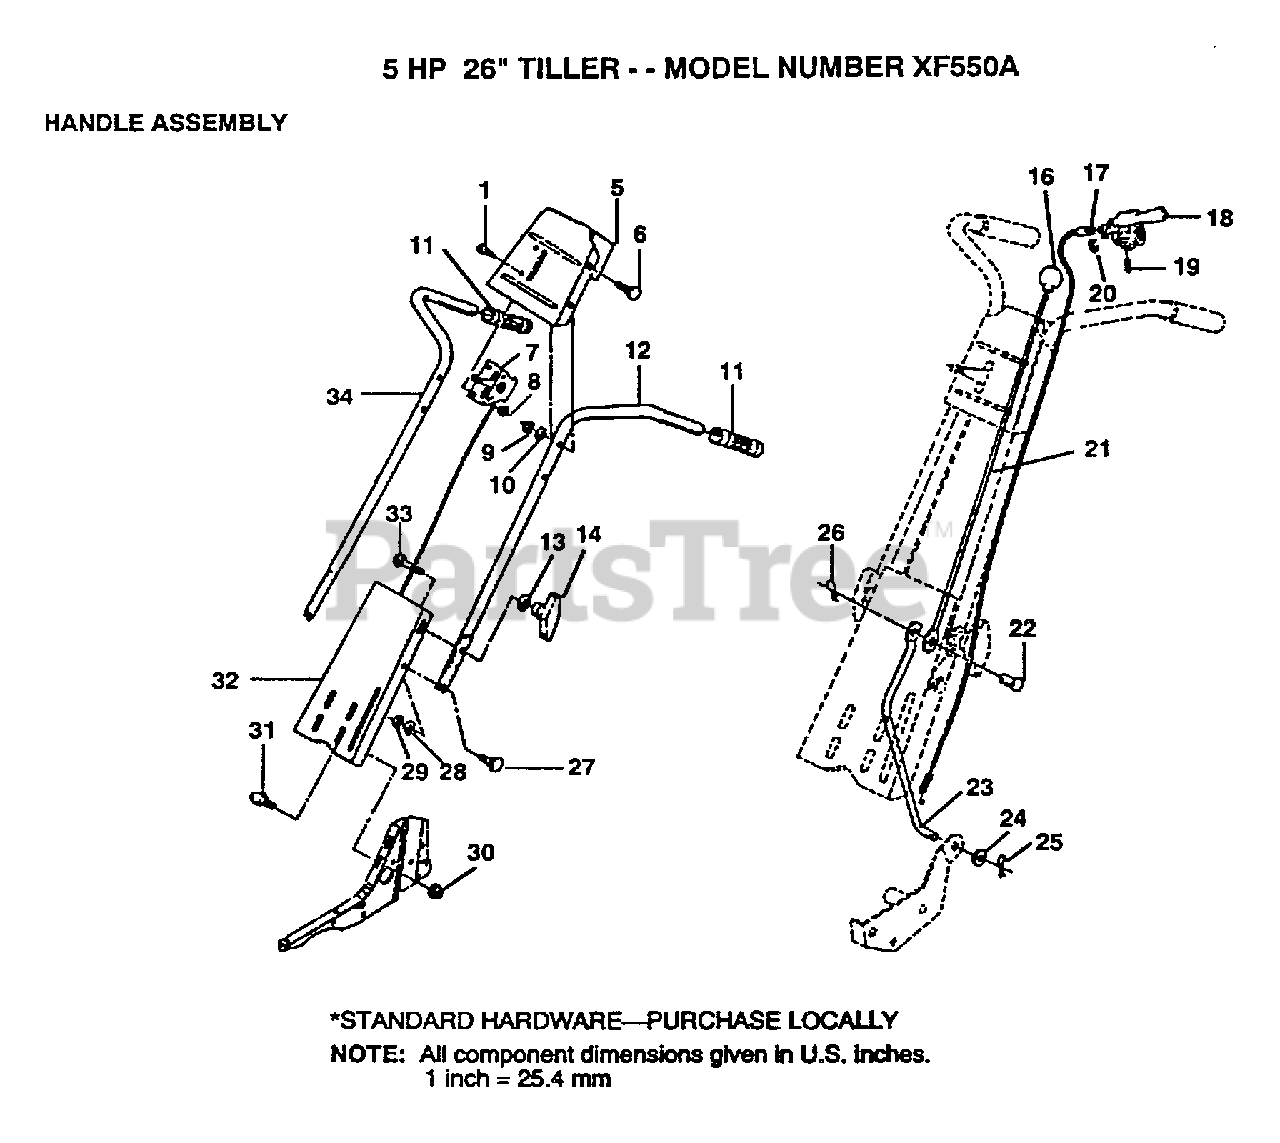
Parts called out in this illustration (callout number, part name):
1	SCREW
6	BOLT
10	WASHER
13	WASHER
17	CABLE CLUTCH T
18	CONTROL LEVER TI
19	SCREW
20	E-RING
21	ROD REVERSE TI
22	RIVET.RD.HD.DRILL
23	REVERSE ROD TI
24	WASHER
25	COTTER PIN
28	LOCKWASHER
29	NUT.HEX.5/16-18
30	NUT
31	BOLT
33	BOLT
